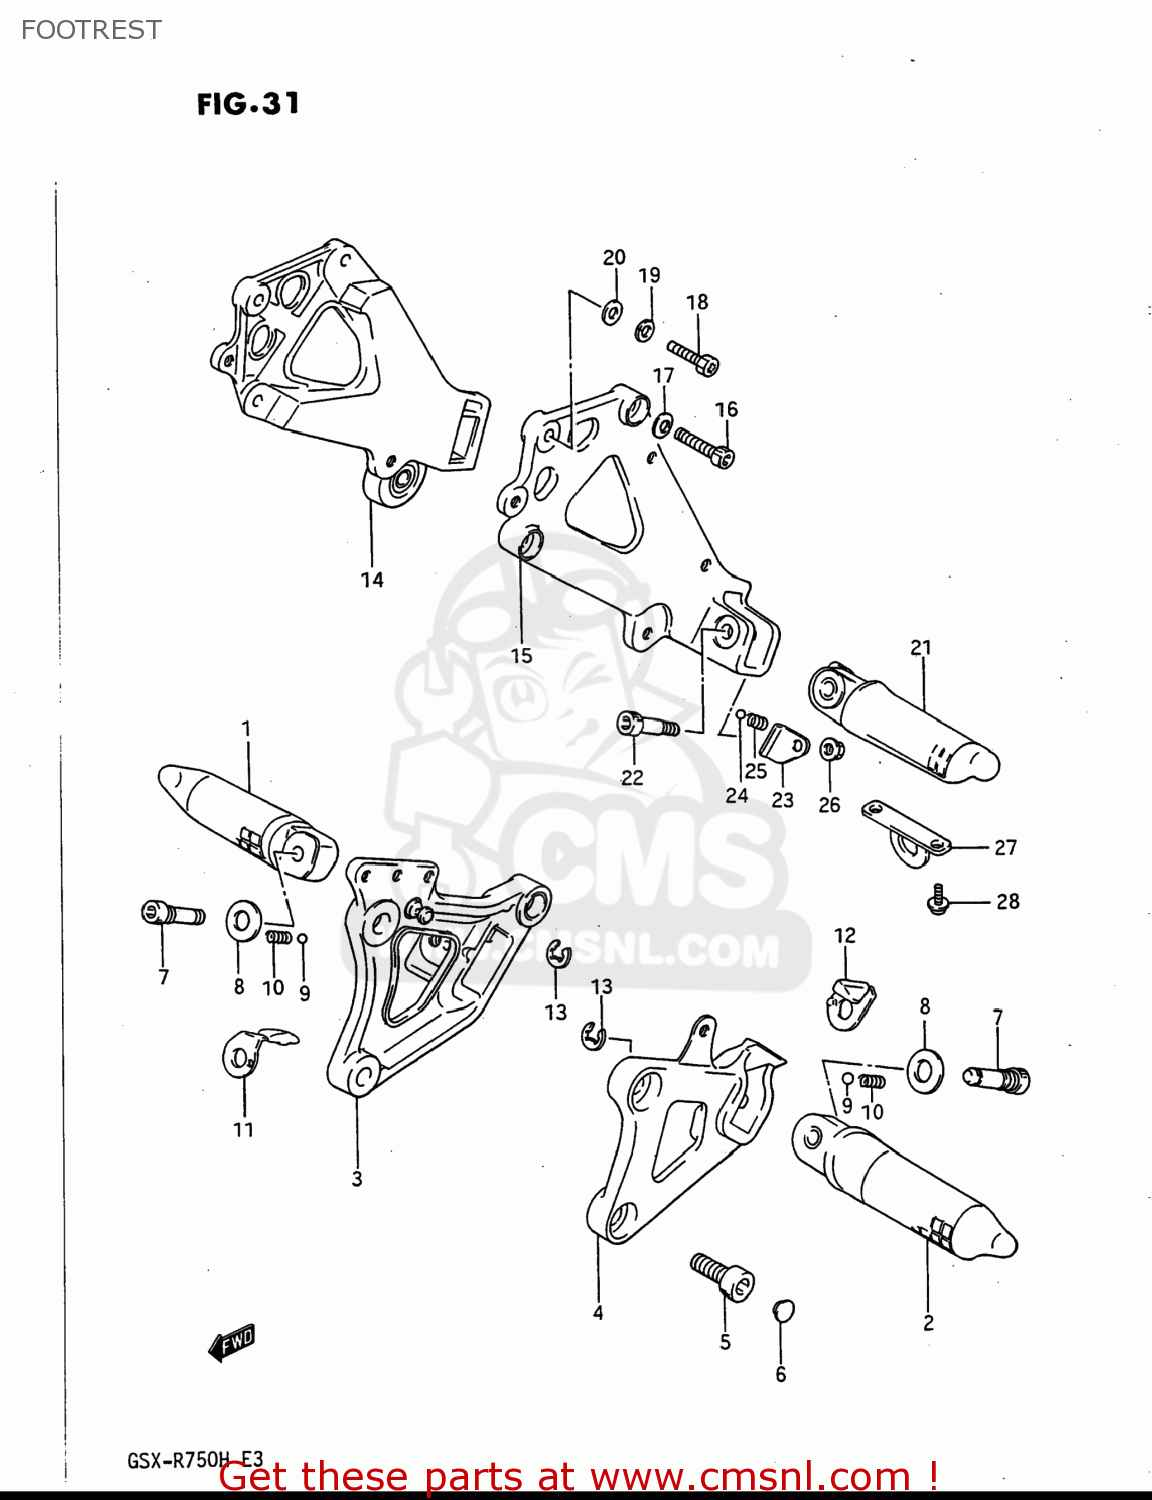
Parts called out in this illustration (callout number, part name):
1	FOOTREST ASSY,FR,R
2	FOOTREST ASSY,FR,L
3	BRACKET,FOOTREST,R
4	BRACKET,FOOTREST,L
5	BOLT
6	CAP
7	BOLT,FR FOOTREST
8	PLATE,SPRING STOP
9	BALL
10	SPRING
11	CUSHION,FRONT FOOTREST,RIGHT
12	CUSHION,FRONT FOOTREST,LEFT
13	E RING 6MM
14	BRACKET
15	BRACKET
16	BOLT
17	WASHER
18	BOLT 6X30
19	WASHER,LOCK
20	WASHER
21	FOOTREST ASSY,PILLION RH
22	BOLT,PILLION FOOTREST
23	PLATE,SPRING STOP LH
24	BALL
25	SPRING
26	NUT
27	HOOK
28	SCREW
